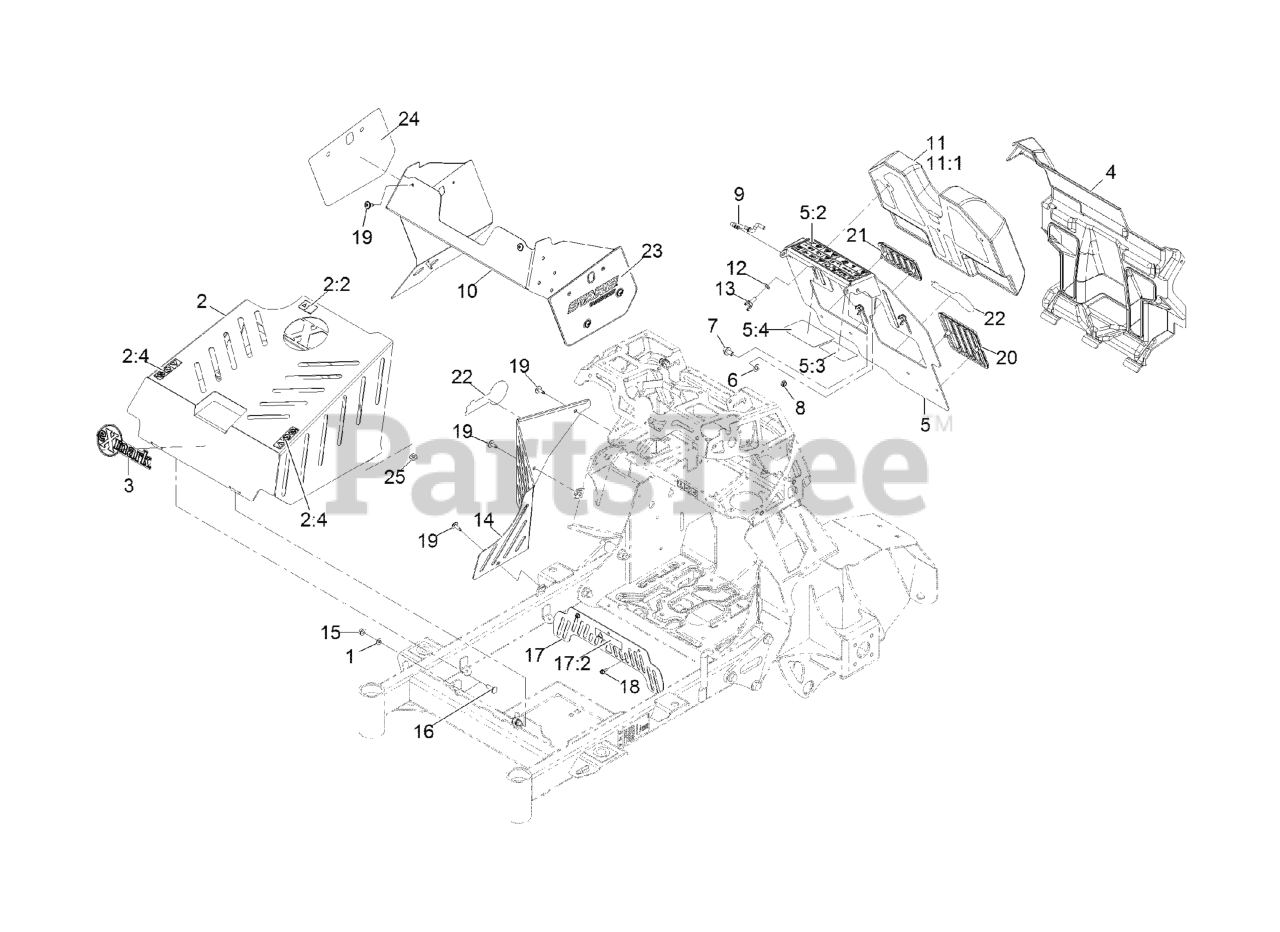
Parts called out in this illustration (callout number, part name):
1	SPACER-NYLON
2	ASM-COVER W DECALS
2:2	DECAL-WARNING
2:4	DECAL-NO STEP/RIDERS
3	DECAL, EXMARK LOGO
4	COVER-REAR
5	ASM, PAD BACKING W/ DECALS
5:2	DECAL-WARNING
5:3	DECAL-DRIVE RELEASE
5:4	DECAL-SERVICE AID SM
6	WASHER-THRUST
7	SCREW-HHF
9	ROD, PROP
10	COVER-TOWER
11	PAD-THIGH
11:1	COVER, PAD
12	WASHER-BELLEVILLE
13	SCREW, THUMB
14	COVER-RH SIDE
16	BOLT-CARR
17	ASM, BELT GUARD W/ DECAL
17:2	DECAL-WARNING
18	SCREW-HWH
19	SCREW, TORX
20	PAD, KNEE, LT
21	PAD, KNEE, RT
22	DECAL-EXMARK LOGO
23	DECAL-STARIS LOGO LT
24	DECAL-STARIS LOGO RT
